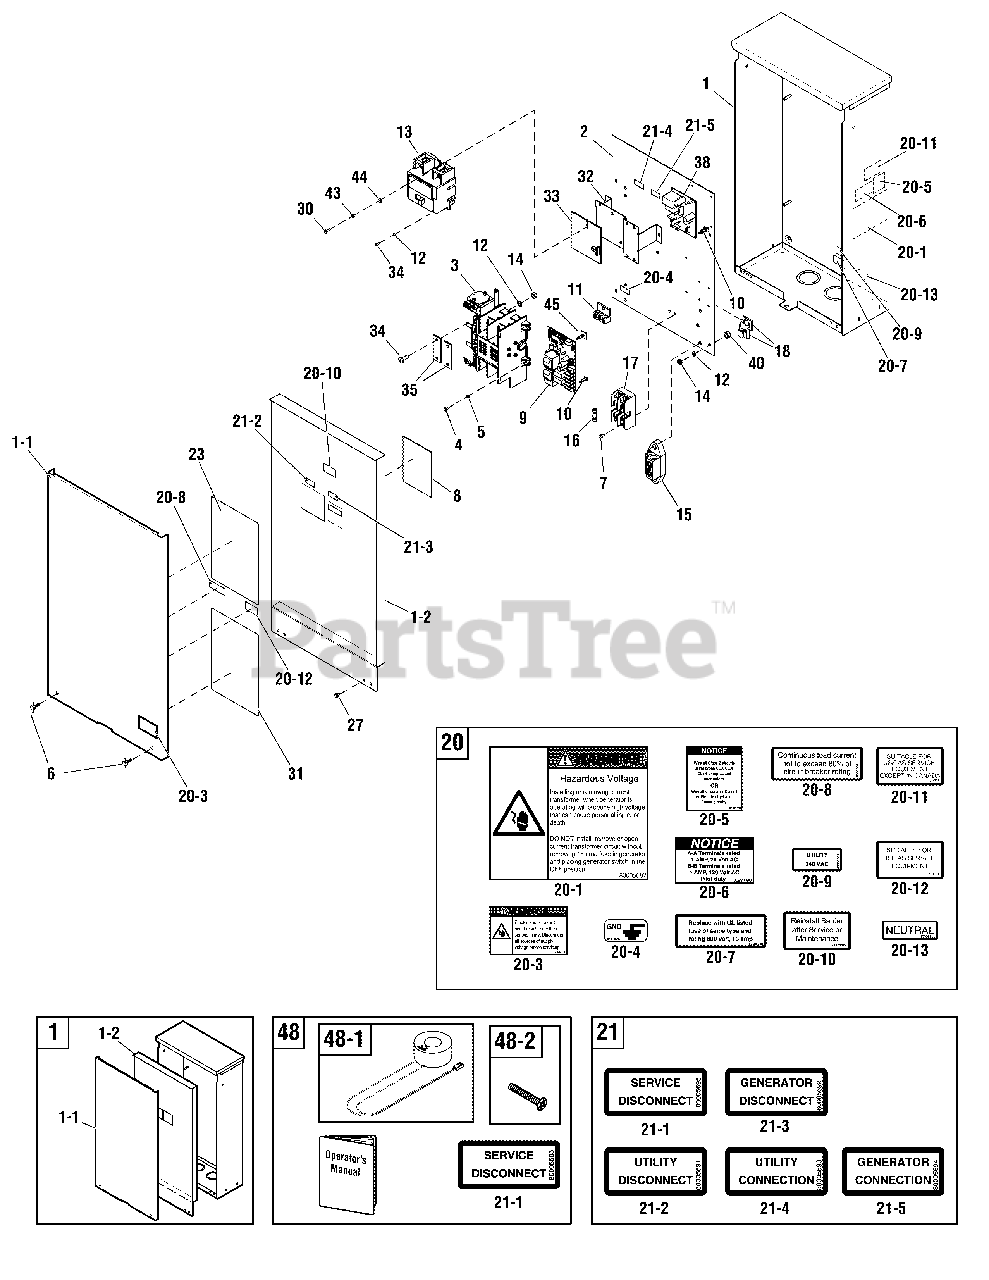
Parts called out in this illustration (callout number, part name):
1	ENCLOSURE
2	BACK PANEL
3	SWITCH, Transfer
4	* TRILOBULAR, #10-32 x 1/2
5	* WASHER, Ext., #10
7	* SCREW, Hex Head, Trilobular, #8-32 x 3/8
9	BOARD, Circuit
11	LUG
12	* WASHER, Lock, 1/4
13	BREAKER, Circuit, 150A
14	* NUT, 1/4-20
20	DECAL SHEET - WARNINGS
20-1	DECAL, Warning Voltage
20-3	DECAL, Warning Shock
20-4	DECAL, Ground
20-5	DECAL, Notice
20-6	DECAL, Contacts Rated
20-7	DECAL, Fuse, 10 Amp
20-8	DECAL, Breaker, Circuit
20-9	DECAL, Sensing, Utility
20-10	DECAL, Reinstall After
20-11	DECAL, Not Suitable
20-12	DECAL, Suit. as Service Equip.
20-13	DECAL, Neutral
21	DECAL SHEET-CONNECTIONS
21-1	DECAL, Service Disconnect
21-2	DECAL, Disconnect Utility
21-3	DECAL, Gen Disconnect
21-4	DECAL, Connection, Utility
21-5	DECAL, Connect Gen
27	TRILOBULAR, #10-32 x 3/8
30	* SCREW, Hex Head, Trilobular, #10-32 x 3/4
34	* SCREW, Pan Head Phillips, 1/4-20 x 3/4
40	SPACER
43	* WASHER, Lock, #10
44	* WASHER, Flat, #10
48	KIT, Manual/ACC
48-1	CURRENT TRANSFORMER
